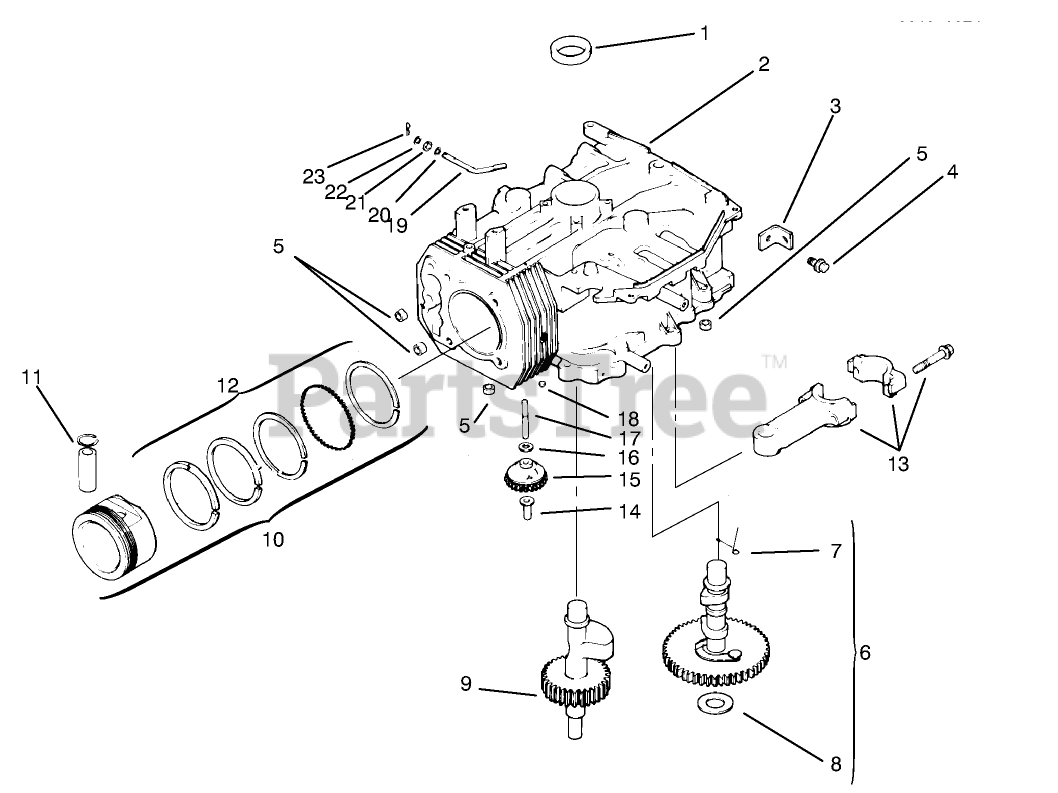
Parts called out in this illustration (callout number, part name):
1	Seal-Crankshaft (Only On: 72042, 72043, 72062, 72063)
2	Block-Short
3	Strap-Lifting (Only On: 72042,72043,72062,72063)
4	Screw M8x1.25x22 (Only On: 72042, 72043, 72062, 72063)
5	Pin-Dowel
6	Kit-Camshaft INC 7-8 (Only On: 72042, 72063, 72062, 72043)
7	Spring-Actuating (Only On: 72042,72043,72062,72063)
8	Shim-Camshaft
9	Shaft-Balance
10	Piston ASM STD Incl 11-2
10	Piston ASM .25 Incl 11-2
10	Piston ASM .50 Incl 11-2
11	Retainer-Piston Pin (Only On: 72042, 72043,72062,72063)
12	Ring Set STD
12	Ring Set .25
12	Ring Set .50
13	Rod Connecting STD
13	Rod Connecting .25
14	Pin-Governor
15	Gear-Governor ASM (Only On: 72042, 72063, 72062, 72043)
16	Washer
17	Shaft-Govenor Gear
18	Cup
19	Kit-Governor Cross
20	Washer, plain 6 mm
21	Seal
22	Washer
23	Clip-Hitch Pin
